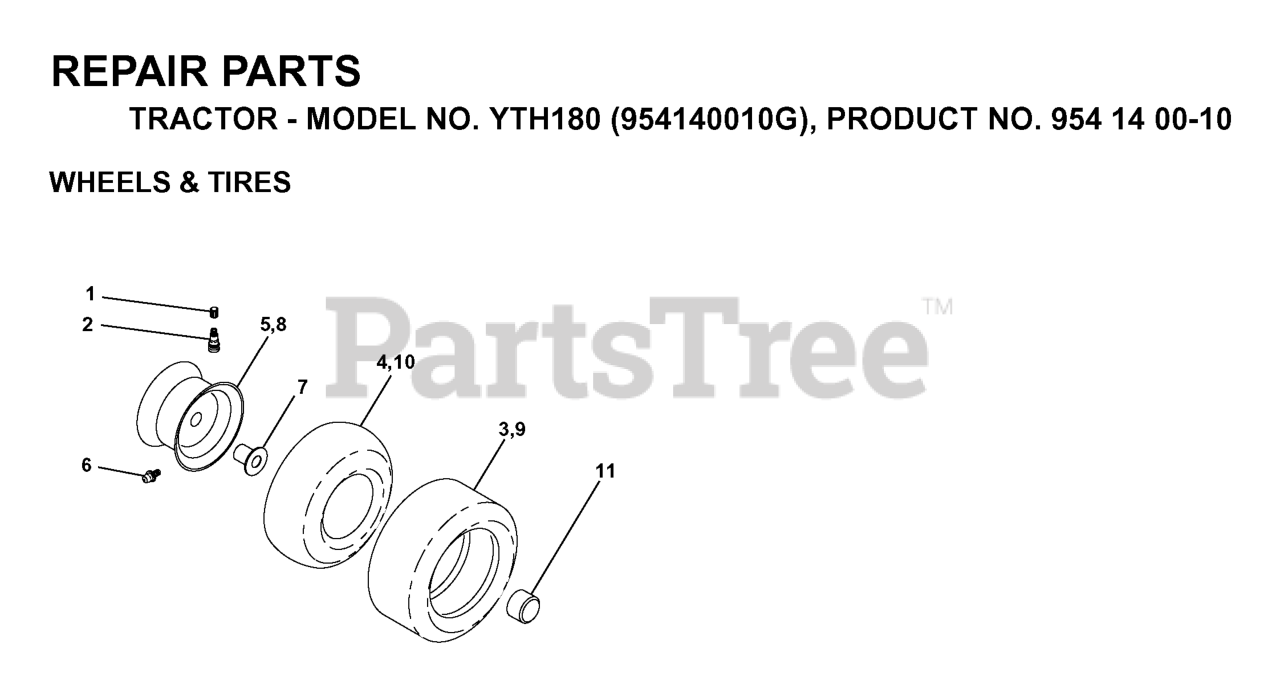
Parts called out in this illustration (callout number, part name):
2	VALVE STEM LT
3	TIRE HEAVY DUTY
4	TUBE.5.3/4.5/6
5	RIM ASM 6" FRONT SILVER
6	FITTING LT
7	BEARING T
8	RIM ASM 8" REAR SILVER
9	TIRE.TS.20X10-8
10	TUBE
11	CAP.HUB.FRONT.LT.BLACK
